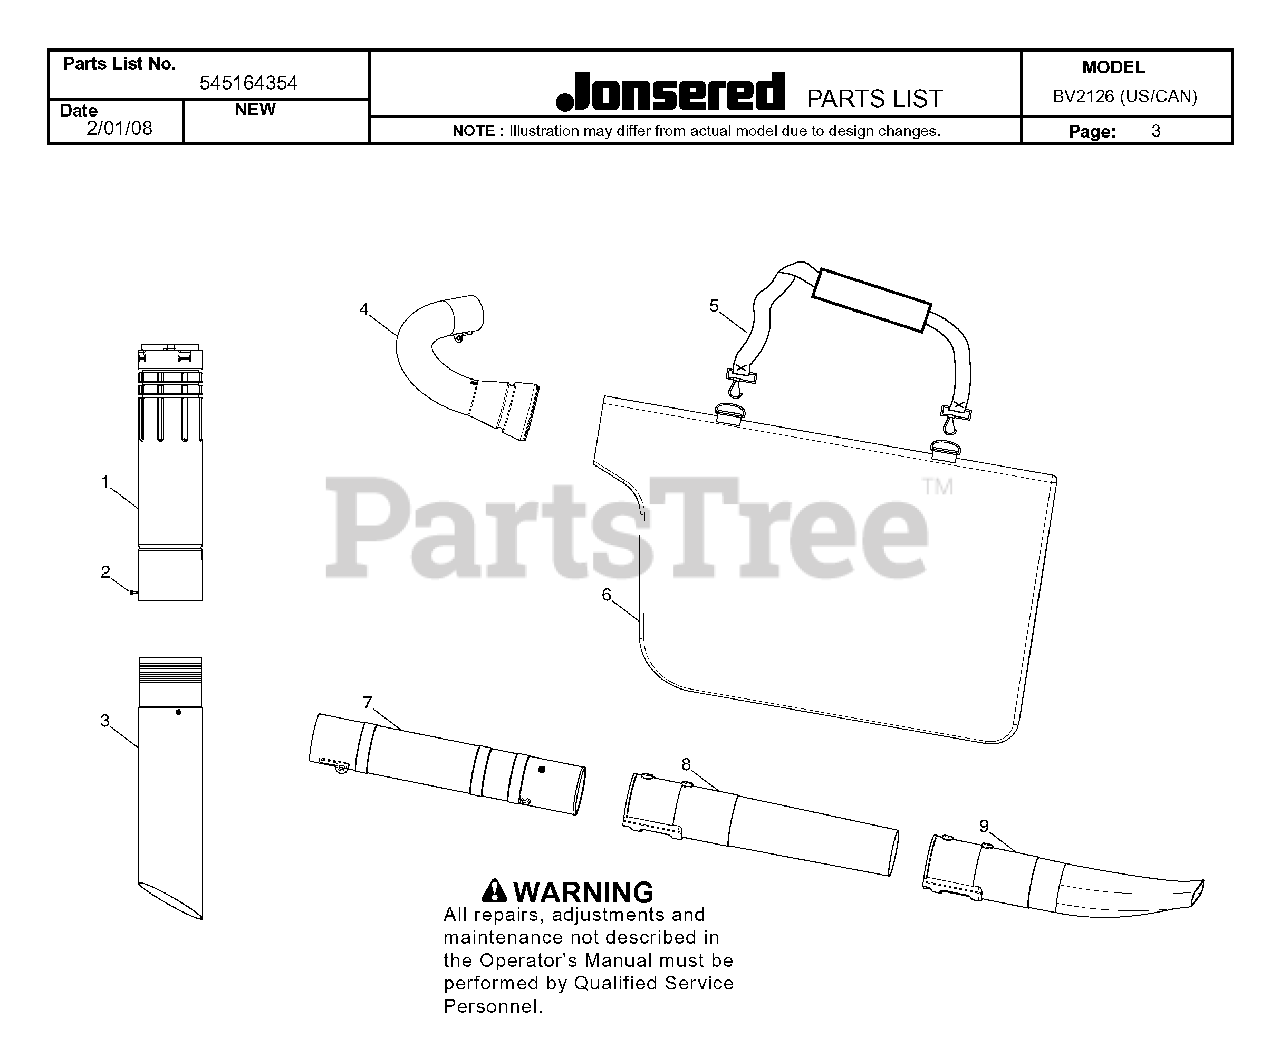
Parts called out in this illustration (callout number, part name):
1	ASSY - UPPER VAC TUBE
3	TUBE - LOWER VAC
4	TUBE - ELBOW
5	%STRAP
6	VACUUM BAG
8	TUBE - LOWER BLOWER
9	TUBE-LOWER BLOWER FLARE
